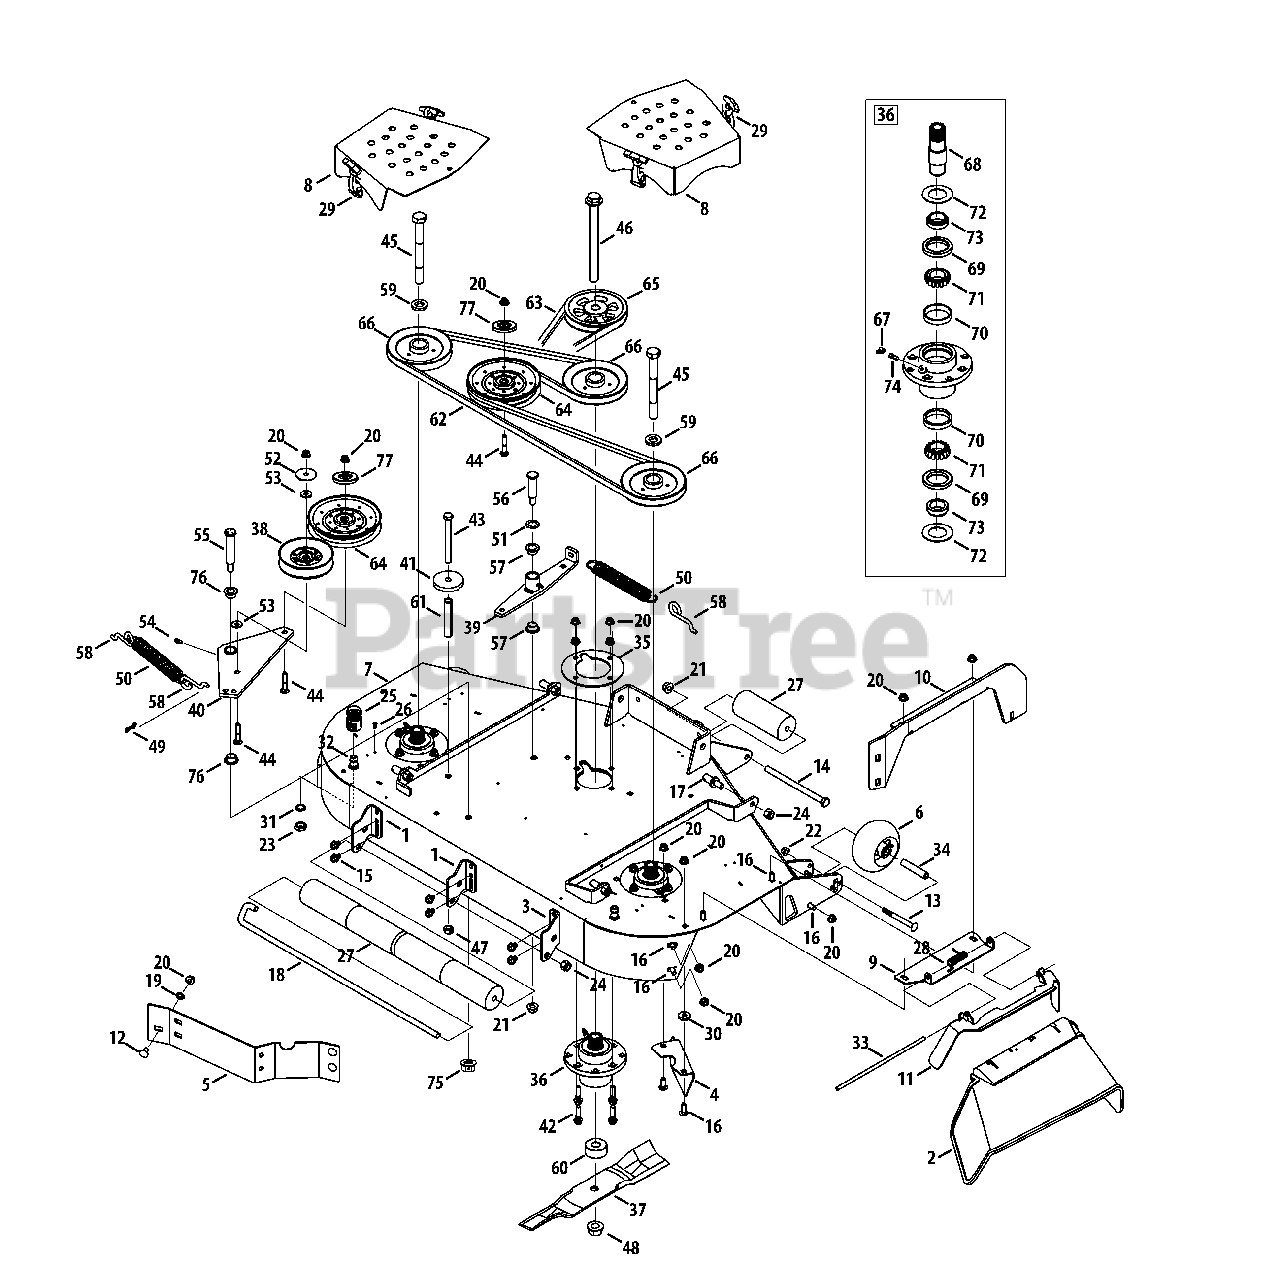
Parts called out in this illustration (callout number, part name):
2	Chute Deflector
5	Baffle, 48" Adjustment
6	Complete Wheel, 5.00 Dia.
7	48" Deck
8	Deck Belt Cover
9	Chute Deflector Bracket
10	Deck Support Plate
11	Chute Extension Bracket
12	Carriage Bolt, 3/8-16 x .750
13	Carriage Bolt, 3/8-16 x 4.00
14	Hex Cap SCrew, 1/2-13 x 7.50
15	Screw, 3/8-16 x .500
16	Carriage Bolt, 3/8-16 x 1.00
17	Pin, 1/2-13 x .625 x 1.2
18	J-Hook w/ Threaded Roller
19	Push Nut, 3/8
20	Nut, 3/8-16, Flangelock
21	Nut, 1/2-13, Flangelock
22	Nut, 3/8-16, Centerlock
23	Hex Nut, M16-1.5
24	Nut, 1/2-13, Hexlock
25	Water Nozzle Adaptor
26	Pop Rivet, 3/16
27	Front Roller
28	Torsion Spring, 0.639 x 2.16
29	T-Handle Latch Draw
30	Washer, .395 x 1.12 x .190
31	Lock Washer, 17 x 23.8 x 1.95
32	Deck Water Nozzle
33	Chute Deflector Rod
34	Wheel Spacer
35	Spindle Support Plate
36	Spindle Assembly
37	Hi-Lift Blade, 17.0
38	Idler Pulley
39	Deck Idler Arm
40	Idler Assembly
41	Spacer, .5375 x 2.75 x .375
42	Carriage Bolt, 3/8-16 x 1.5
43	Hex Cap Screw, 1/2-13 x 5.00
44	Carriage Bolt, 3/8-16 x 2.00
45	Hex Cap Screw, 3/4-16 x 7.00
46	Hex Cap Screw, 3/4-16 x 9.00
47	Nut, 1/2-13, Hexlock
48	Nut, 3/4-16, Flangelock
49	Bow Tie Cotter Pin
50	Extension Spring, 1.248 x 8.5
51	Washer, .793 x 1.24 x .06
52	Washer, .406 x 1.92 x .060
53	Washer, .406 x 1.00 x .105
54	Grease Fitting
55	Shoulder Bolt, 1.0 x 3.15, 5/8-18
56	Shoulder Bolt, .750 x 2.23, 1/2-13
57	Flange Bearing, .75 x .52
58	Spring Rod Hook
59	Spacer, .812 x .218
60	Spacer, .760 x 2.00 x .925
61	Spacer, .405 x .75 x 3.875
64	Idler Pulley
65	Drive Pulley
66	Spindle Pulley
67	Grease Fitting, 45 degree, 1/4-28
68	Spindle Shaft
69	Seal, Oil
70	Cup Bearing
71	Cone Bearing
72	Washer, 1.50 x 2.52 x .075
73	Ring, Seal
74	Straight Adapter Fitting
75	Nut, 5/8-18, Flangelock
76	Flange Bearing, 1.00 x .75
77	Pulley Cap
